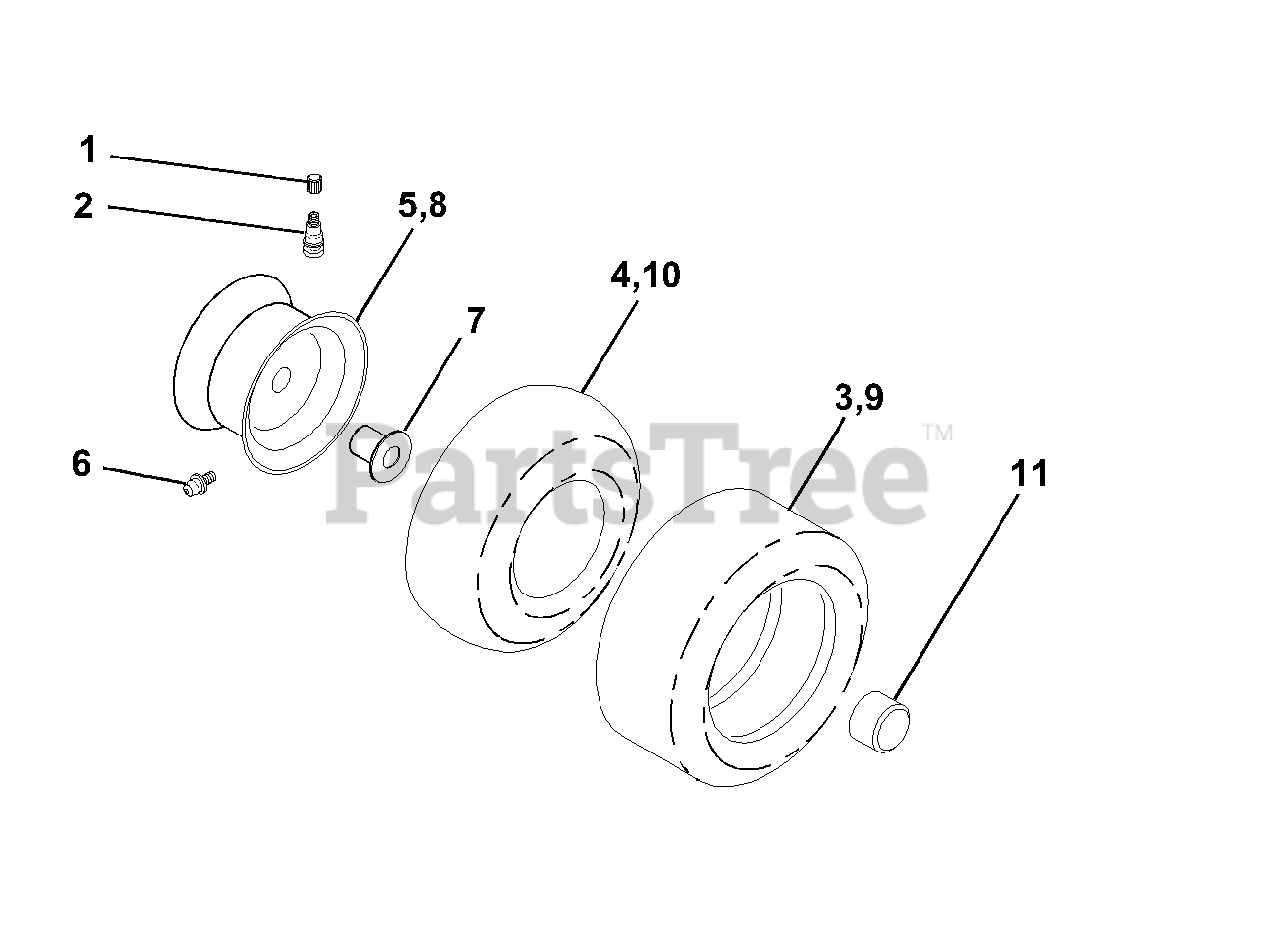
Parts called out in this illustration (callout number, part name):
1	Cap Valve Tire
2	Stem Valve
3	Tire F Ts 15 X 6 0 - 6 Service
4	Tube Front
5	Rim Asm 6" front White Service
6	Fitting Grease
7	Bearing Flange
8	Rim Asm 8" rear White Service
9	Tire R Ts 18x9.5-8 C Service
10	Tube Rear
11	Cap Axle Blk 1 50 X 1 00
